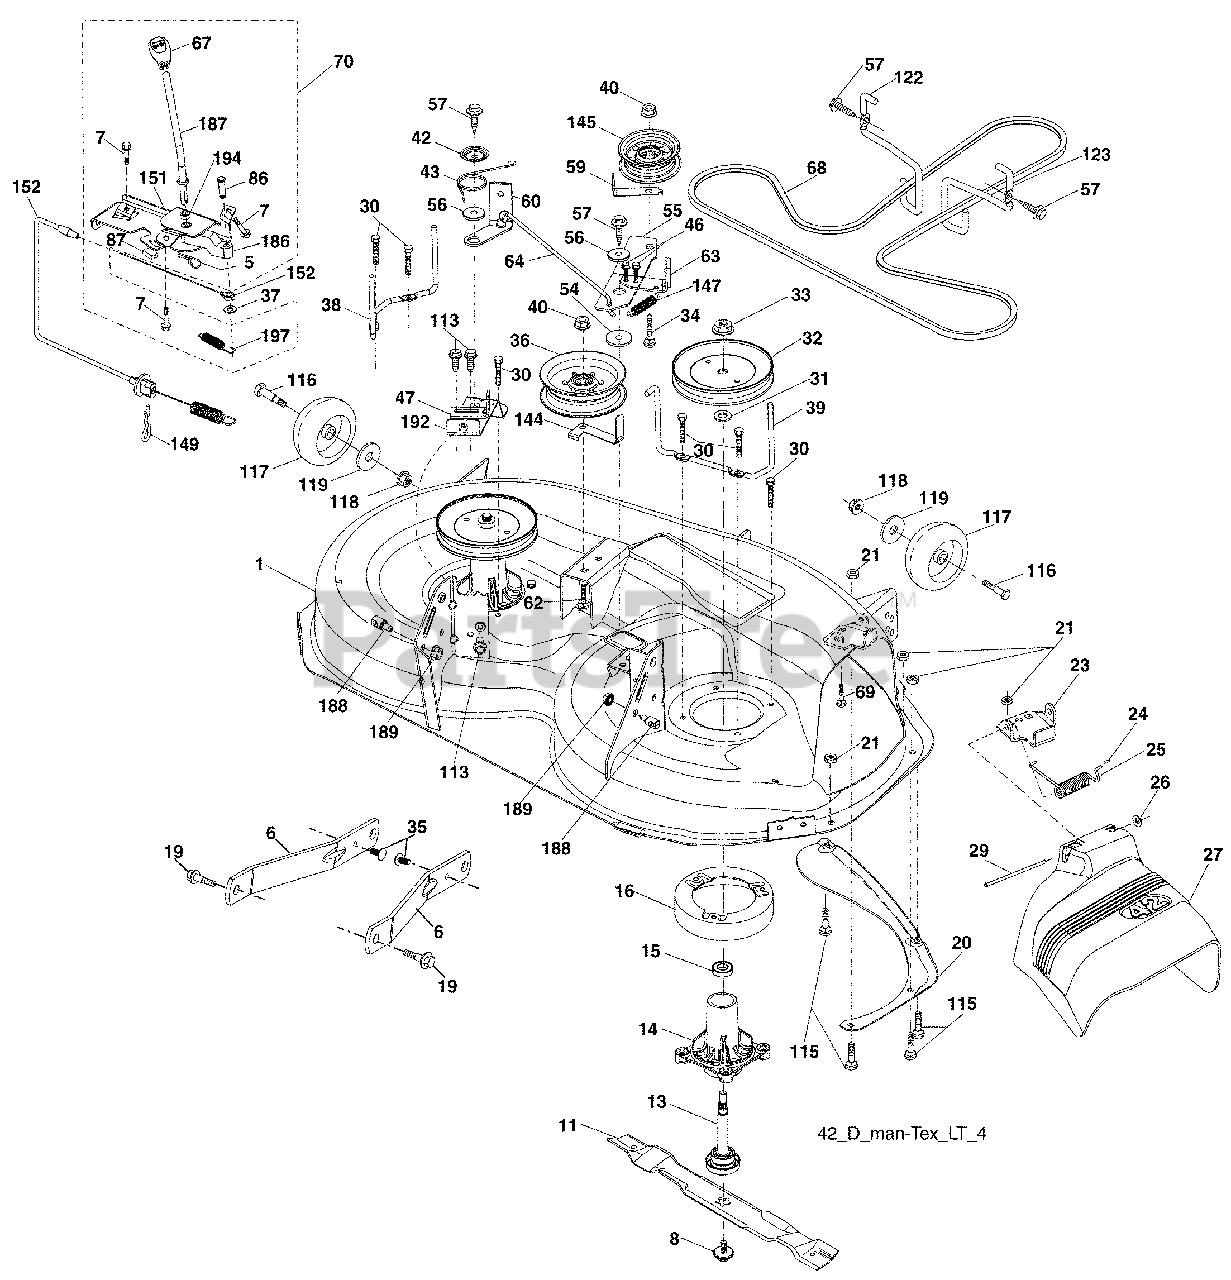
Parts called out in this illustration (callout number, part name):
1	Mower Housing
5	Retainer Spring
6	Arm Suspension
7	Screw 10 x 3/4 Single Lead Hex
8	Bolt/Washer asm 7/16-20 unf
11	Blade, 42" Hi-Lift
13	Shaft Assembly, Mandrel
14	Housing, Mandrel
15	Bearing, Ball, Mandrel
16	Stripper, Mower Deck
19	Bolt, Shoulder
20	Baffl e, Vortex
21	Nut, Crownlock 5/16-18 unc
23	Bracket, Defl ector
24	Cap, Sleeve
25	Spring, Torsion, Defl ector
27	Shield, Defl ector
29	Rod, Hinge
30	Screw Thdrol Rolling Wsh Hd
31	Washer, Spacer
32	Pulley, Mandrel
33	Nut, Toplock, Flanged
34	Bolt Carr Sh. 3/8-16 x 1-1/2 Gr. 5
36	Pulley, Idler, Flat
37	Washer
38	Keeper Belt LH Mandrel
39	Keeper Belt RH Mandrel
40	Nut, Lock Flg. 3/8-16 unc
42	Spring Torsion Brake
43	Spring Torsion Retainer
46	Screw Thd Roll 1/4-20 x 5/8
47	Bracket Clutch Cable
54	Washer, Hardened
55	Arm, Idler
56	Spacer, Retainer
57	Screw 3/8-16 x 1
59	Guard, Tuv Idler
60	Arm Brake Mower
62	Bolt Rd Hd Sq Nk 3/8-16 unc x 2
63	Arm Brake Mower
64	Link Brake LH
65	Spacer Retainer
67	Handle Clutch Cable
68	V-Belt
69	Bolt
70	Clutch Asm Manual
86	Pin Attachment Cable
87	Switch Interlock Clutch Cable
88	Screw 10-24 x 5/8
113	Screw 5/16-18
115	Bolt Carr. 5/16-18 x 5/8
116	Bolt, Shoulder
117	Wheel, Gauge
118	Nut, Crownlock 3/8-1
119	Washer 13/32 x 7/8 x 14 Ga.
122	Keeper Belt Engine LH
123	Keeper Belt Engine RH
144	Keeper Belt
145	Pulley Idler
147	Spring Return
149	Retainer Spring
151	Bracket
152	Manual Clutch Cable
186	Arm Actuator
187	Lever Control Clutch
188	Stud Fastener
189	Nut Lock Hex Flange
192	Bracket Brake Stand LH
194	Bearing Control Lever Clutch
197	Spring Plunger Actuator
